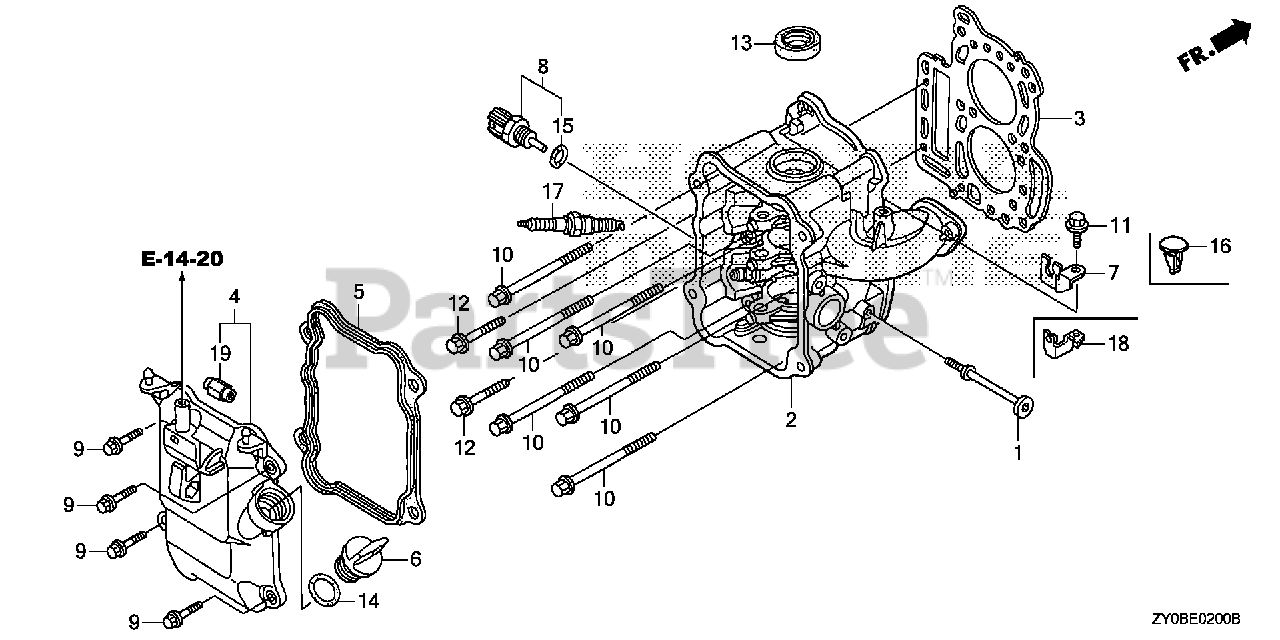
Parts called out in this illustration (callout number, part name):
1	STOPPER, ENGINE SIDE
2	CYLINDER HEAD *NH8* (DARK GRAY)
3	GASKET, CYLINDER HEAD
4	COVER, HEAD
5	GASKET, HEAD COVER
6	CAP, OIL (YELLOW)
7	HOLDER, CABLE
8	SENSOR ASSY., WATER TEMPERATURE
9	BOLT, FLANGE (6X22)
10	BOLT, FLANGE (8X83)
11	BOLT, FLANGE (6X14) (CT200)
12	BOLT, FLANGE (8X40)
13	OIL SEAL (20X32X6)
14	O-RING (26X2.7)
15	O-RING (9.5X1.5) (HONDA KIKAKI)
17	SPARK PLUG (CR5EH-9)
17	SPARK PLUG (U16FER9)
18	HOLDER, CABLE
19	NUT, INSERT
